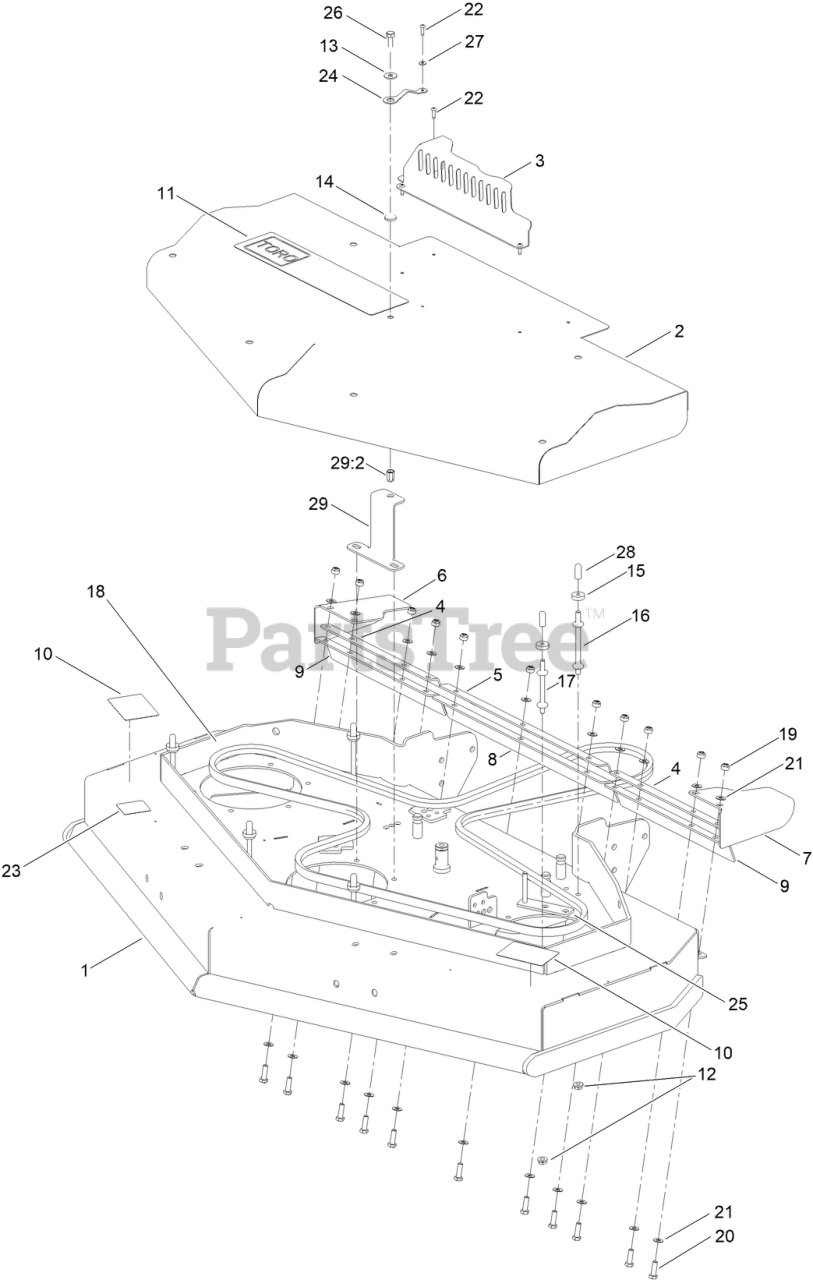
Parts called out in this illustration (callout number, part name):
1	48 INCH DECK ASM
2	COVER-DECK
3	GUARD-PIPE, EXHAUST
4	BRACKET-DEFLECTOR, SIDE
5	BRACKET-DEFLECTOR, CENTER
6	GUARD-DISCHARGE, RH
7	GUARD-DISCHARGE, LH
8	DEFLECTOR-CENTRE, RUBBER
9	DEFLECTOR-SIDE
10	DECAL-DANGER, CE
11	DECAL-MIDSIZE
12	NUT-HF
13	WASHER
14	NUT-RETAINER
15	WASHER
16	STUD-SHIELD, BELT (LONG)
17	STUD-SHIELD, BELT (SHORT)
18	BELT-V
19	NUT-NYLOC
20	SCREW-HH
21	WASHER
22	RIVET
23	DECAL-NOISE
24	LANYARD-3 INCH
25	GUIDE-BELT
26	SCREW-HH
27	WASHER
28	CAP-END, RUBBER
29	BRACKET-GUARD
29:2	NUT-RIVET
